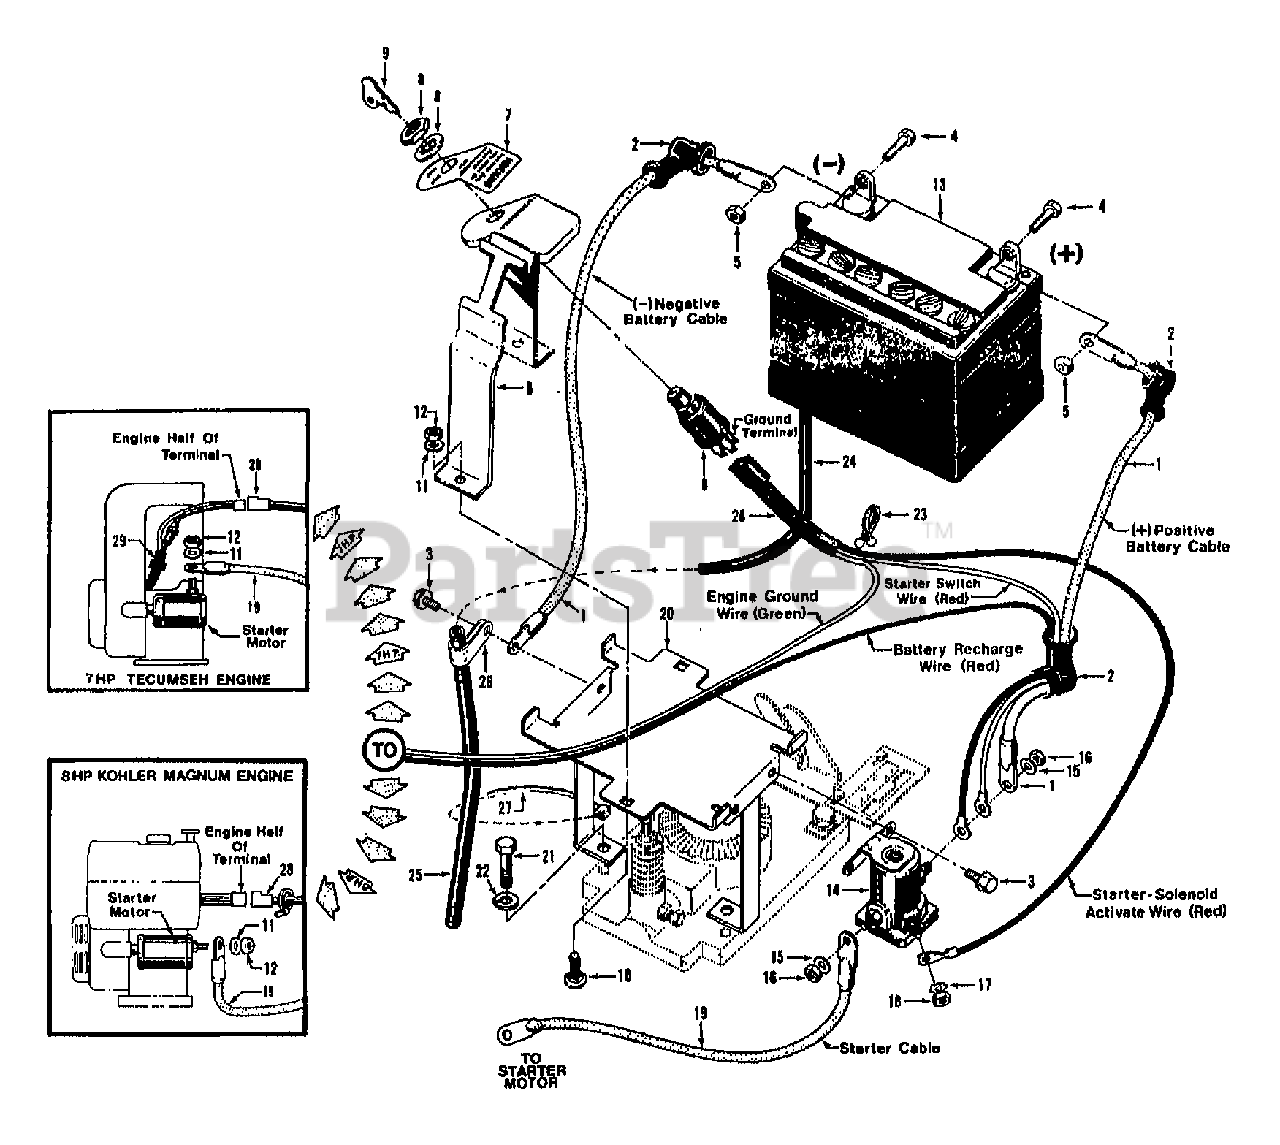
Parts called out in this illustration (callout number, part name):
1	CABLE-BATTERY
3	SCR-HWH 1/4-20 X .5 STH
4	SCR-HHC 5/16-18X.75 GR 5 ZP
5	NUT-HEX 5/16-18 ZP
6	CLAMP-KEYSWITCH W/DECAL OPC
7	DECAL-KEYSWITCH
8	KEYSWITCH W/KEYS
9	KEYS(1 PAIR) FOR SWITCH
10	SCR-CARR 1/4-20X1.5
11	WASHER-LK .25 ZP
12	NUT-HEX 1/4-20 ZP
13	BATTERY-12 VOLT HORSE
14	KIT-SOL W/HDW
15	WASHER-LK .312 ZP
16	NUT-HEX 5/16-24
17	WASHER-EXTERNAL TOOTH 1
18	NUT-HH M10-32X.125
19	CABLE-BATTERY
20	BRKT-BATTERY OPC PNT
21	BOLT-HH 3/8-16X1.5 FTH ZP
22	WASHER-LK .375 @ DEPL
23	TIE-TWIST LOCK
24	TUBE-VENT BATTERY/HSE
25	TUBING-RUBBER
26	CLAMP
27	TIE-RED
28	HARNESS-WIRE 3.5
29	DIODE BATTERY RECHARGIN FOR TEC. ENGINE.
